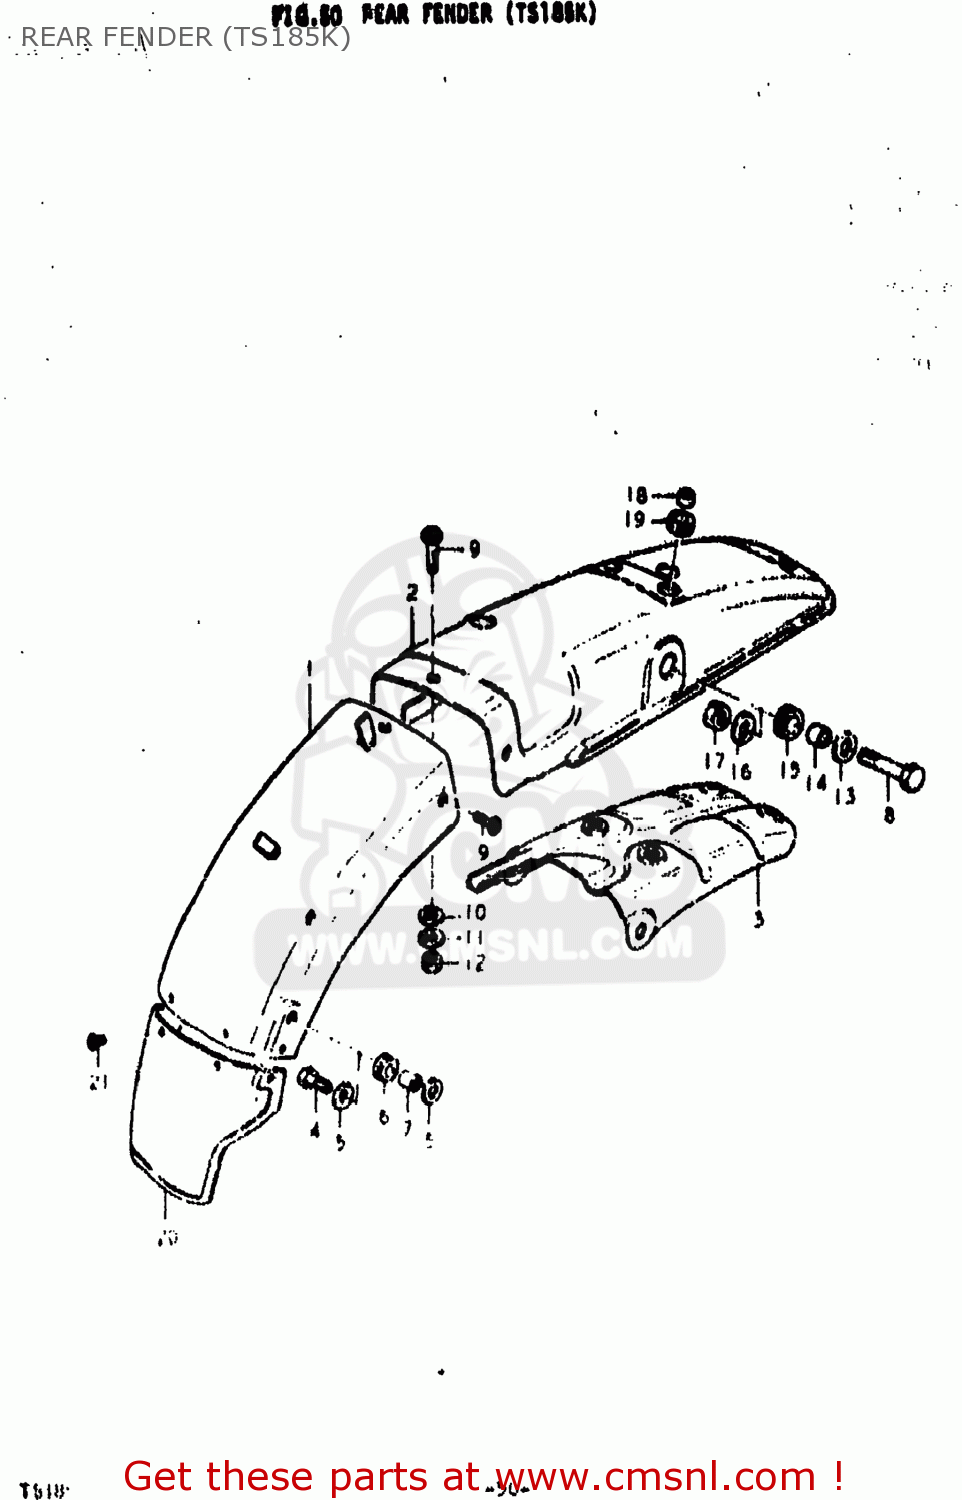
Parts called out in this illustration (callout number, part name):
1	FENDER,REAR
2	FENDER,REAR
3	REINFORCEMENT,REAR FENDER
4	BOLT
5	WASHER (6.5X20X1.2)
6	CUSHION
7	SPACER(6.1X9X7.5)
8	BOLT
9	SCREW
10	WASHER 5MM
11	LOCK WASHER
12	NUT
13	WASHER
14	SPACER
15	CUSHION
16	LOCK WASHER
17	NUT
18	SPACER(6.1X9X7.5)
19	CUSHION
20	MUD GUARD,REAR FENDER
21	SCREW
